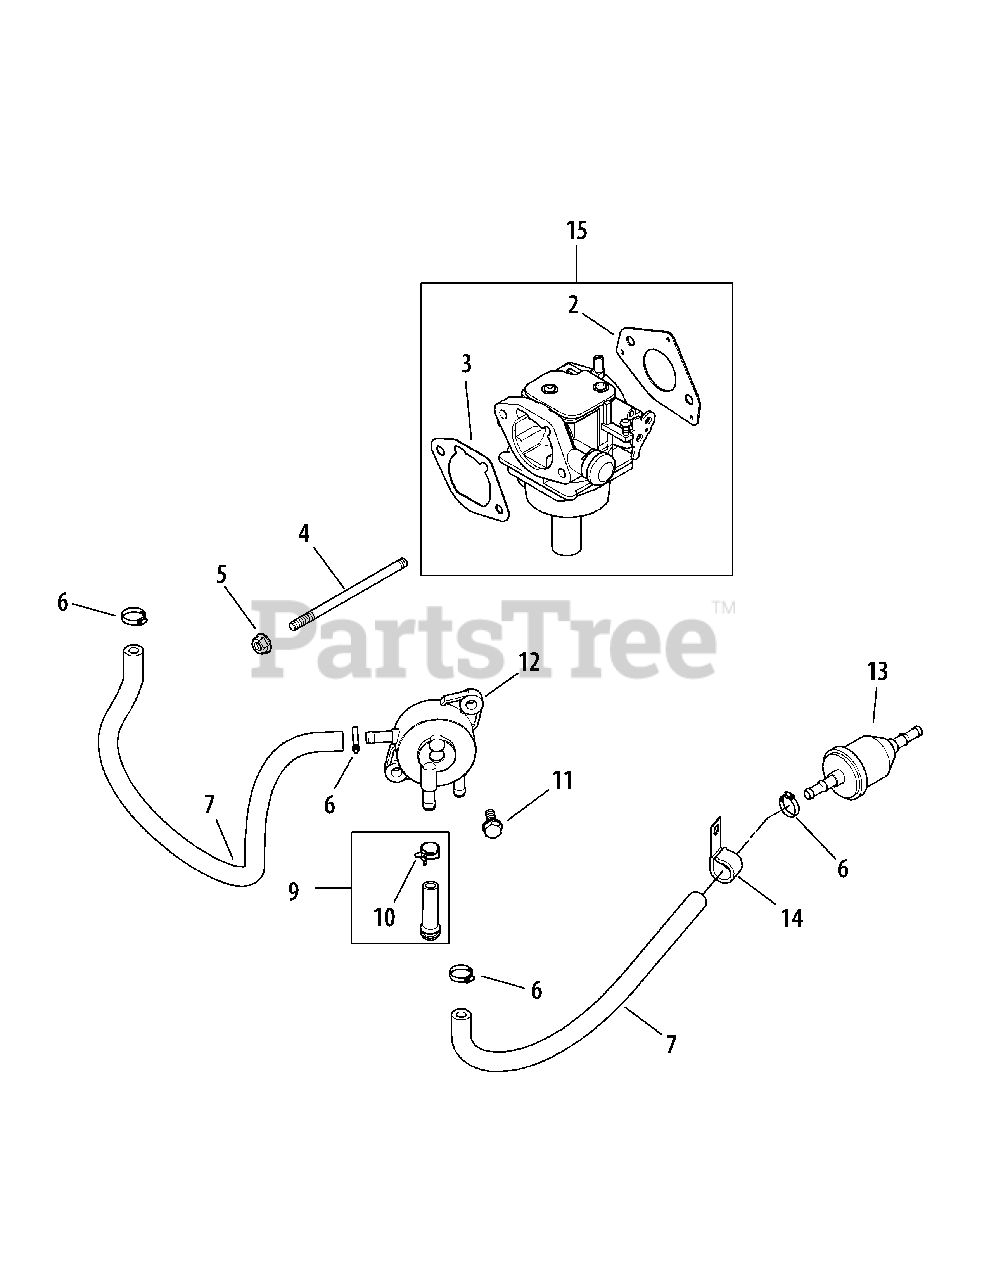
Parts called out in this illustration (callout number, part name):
2	Carburetor Gasket
3	Air Cleaner Base Gasket
4	Stud, M6 X 1.0 X 106
5	Flg. Nut, M6 X 1.0
6	Hose Clamp, 1/2
7	Fuel Line
11	Tap Screw, M6 X 1.7 X 18
15	Carburetor Kit, 19mm (Inc. 2 & 3)
